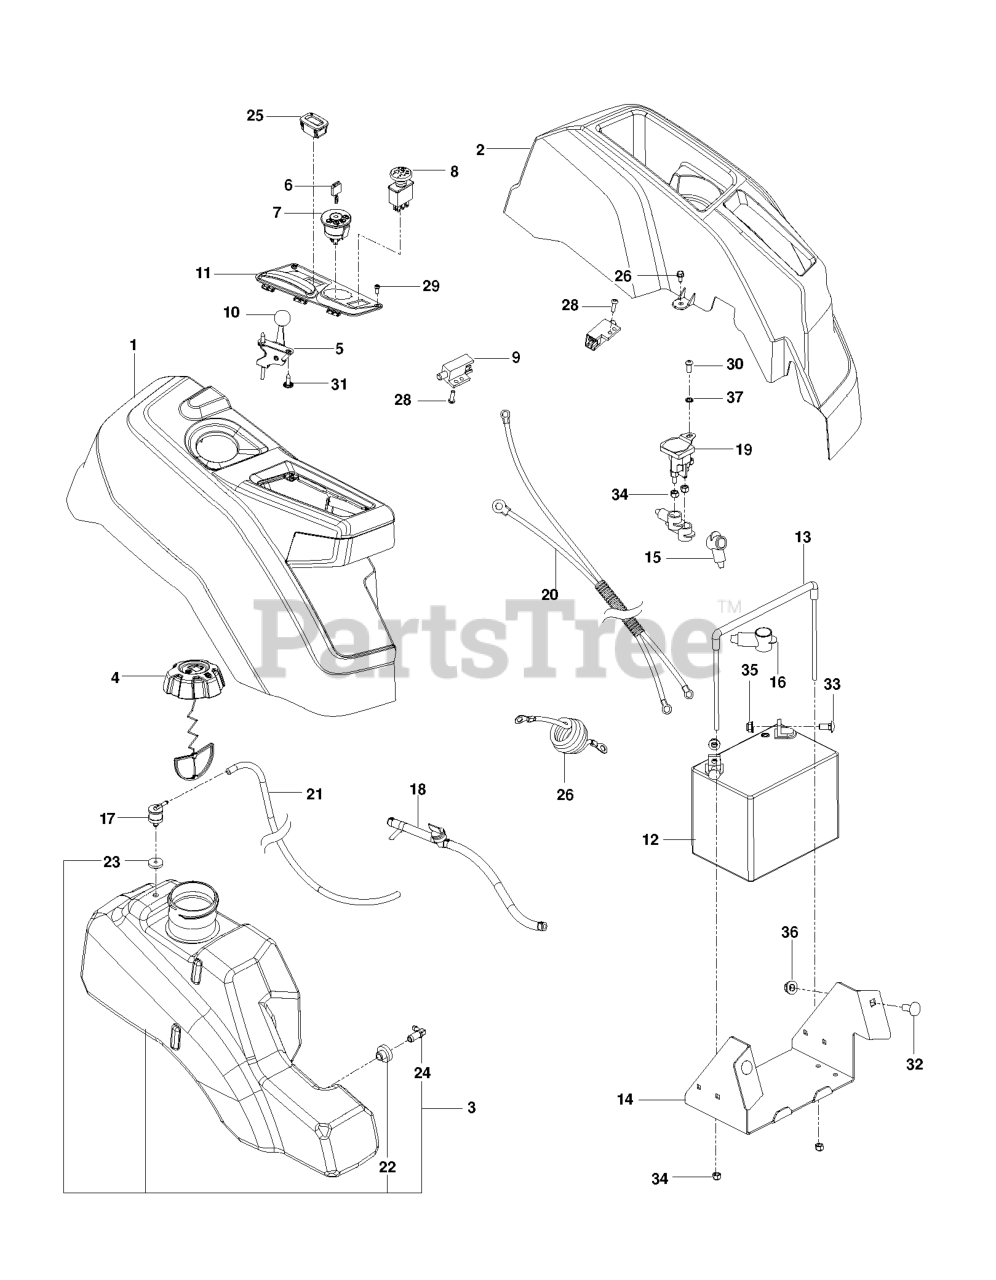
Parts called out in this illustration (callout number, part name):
1	CONSOLE.ASSY.RZ.REFRESH.RH
2	CONSOLE.LH.ASM
3	ASM.FUEL.TANK.LG.3".W/O SHIELD
4	CAP ASSY FUEL 3" GRAY
5	CABLE.THROTTLE.37"
6	KEY MLD GEN DELTA
7	RP IGNITION SWITCH
8	RP SWITCH.PTO.8.TERMINAL.RED
9	SWITCH INTERLOCKT
10	KNOB.ROUND.BALL.BLACK
11	CONTROL.PANEL.RZ.REFRESH.RH
12	BATTERY, 12 V 330 AMP
13	BATTERY TIE DOWN ASSEMBLY
14	BOX BATTERY RZ BLACK
15	TERMINAL COVER
17	VALVE.FUEL.CHECK
18	FUEL.HOSE.SHUT.OFF.ASM.10".3"
19	SOLENOID.W/BRASS.PLUNGER
20	HARNESS.BTTRY.CABLE.RZ.REFRESH
21	HOSE.3/16".VAPOR.LINE.64"LGTH
22	BUSHING OUTLET T
23	GROMMET.ROV.SENTEC
24	STEM FUEL TANK
25	GUAGE.SRVCMNDR.HRMTR.
26	CABLE POSITIVE, LONG
27	SCREW.PAN.HEAD.#10
28	SCR #10-24 X .75 SKT HD BLK
29	SCREW 6-19X.437
30	SCR 1/4-20 X 5/8 BTN SKT HD ZD
31	SCREW
32	RHSNB 3/8C X 1
33	RP BOLT 5/16-18 X3/4 ZN/YEL GR
34	LOCKNUT.NYLOC.1/4-20
35	5/16-18 NYLOC FLANGE NUT
36	NUT 3/8-16 HEX FLG NYLOC ZD
37	WASHER 1/4 INT TOOTH
